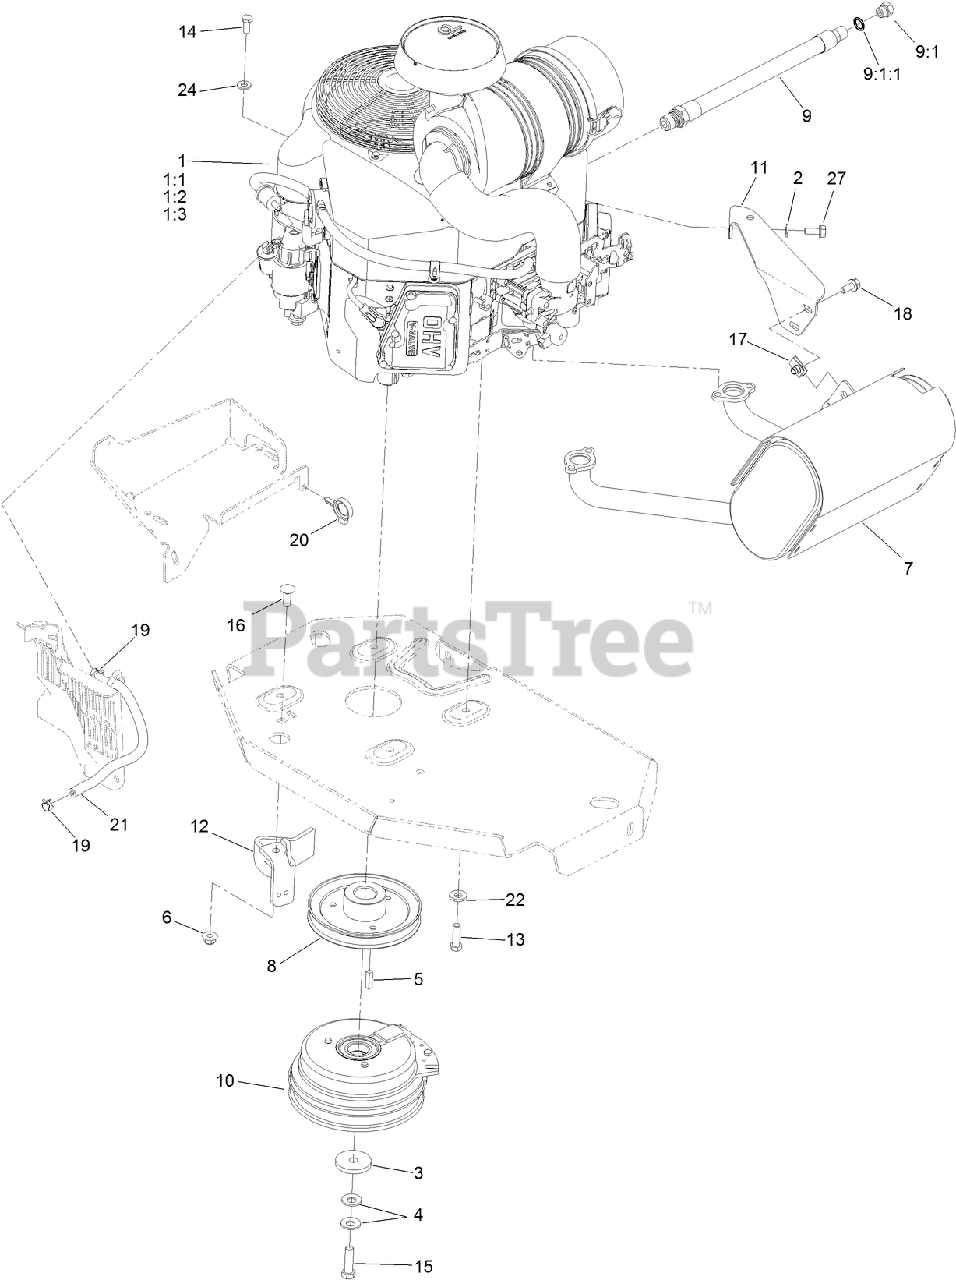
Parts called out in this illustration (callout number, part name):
1:1	KAWASAKI 49065-7007 ENGINE OIL FILTER
1:2	KAWASAKI 11013-7044 ENGINE AIR FILTER
1:3	KAWASAKI 11013-7045 SAFETY FILTER
2	WASHER-SPRING
3	WASHER-CLUTCH
4	WASHER-SPRING
6	NUT-HF, NI
7	MUFFLER
8	SHEAVE
9	ENGINE OIL DRAIN HOSE ASM
9:1	PLUG-HH
9:1:1	O-RING
10	CLUTCH KIT
11	BRACKET-MUFFLER
12	CLUTCH-ANCHOR
13	SCREW-HH
14	SCREW-HH
15	SCREW-HH, W/LOCTITE
16	SCREW-CARR
17	NUT-U
18	SCREW-HH
19	CLAMP-HOSE
20	CLAMP-HOSE
21	HOSE-FUEL
22	WASHER-BELLEVILLE
24	WASHER-PLAIN
27	SCREW-HHF
